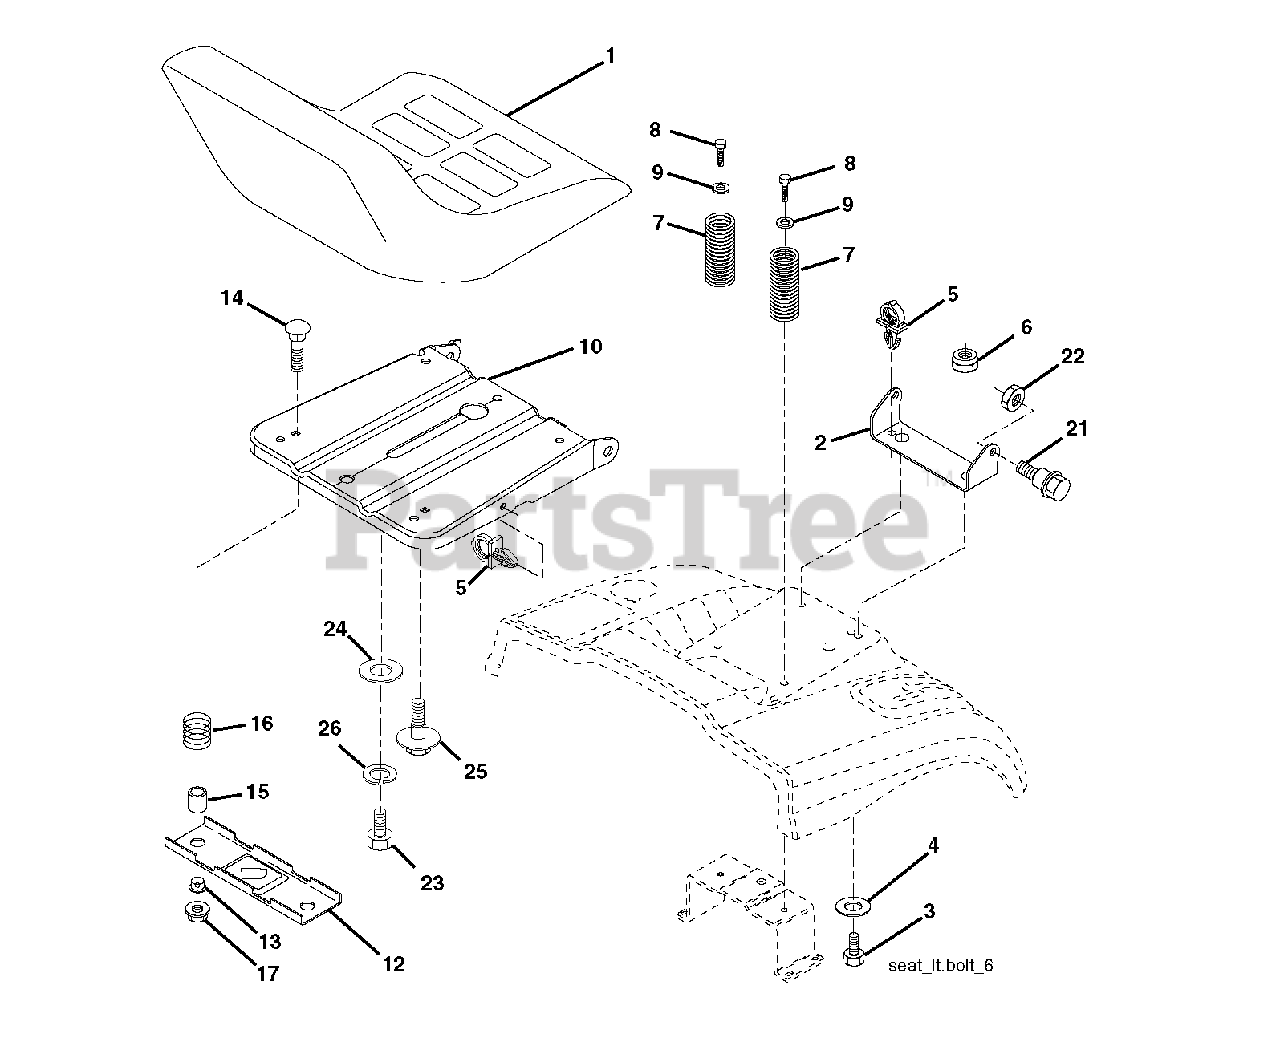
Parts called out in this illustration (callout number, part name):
1	SEAT.XG090.BLK.KB/BLT.NO-LOG
2	SEAT PIVOT BRKT
4	WASHER PM
5	PUSH CLIP
6	NUT
7	SPRING COMPRESSION
8	SCREW 3/8-16X1
9	WASHER
10	PAN.ASM.SEAT.1SLOT
12	BRKT.MNTNG.SWITCH.SEAT
14	BOLT.ROUND.HEAD.SQUARE.NECK
15	SPACER SPLIT 28X.96
17	NUT T
21	BOLT.SHOULDER.5/16-18
22	NUT.71038.31-18.HEX.NYLOCK
23	BOLT.HEX.BLACK
25	BOLT,SHOULD
26	LOCKWASHER
